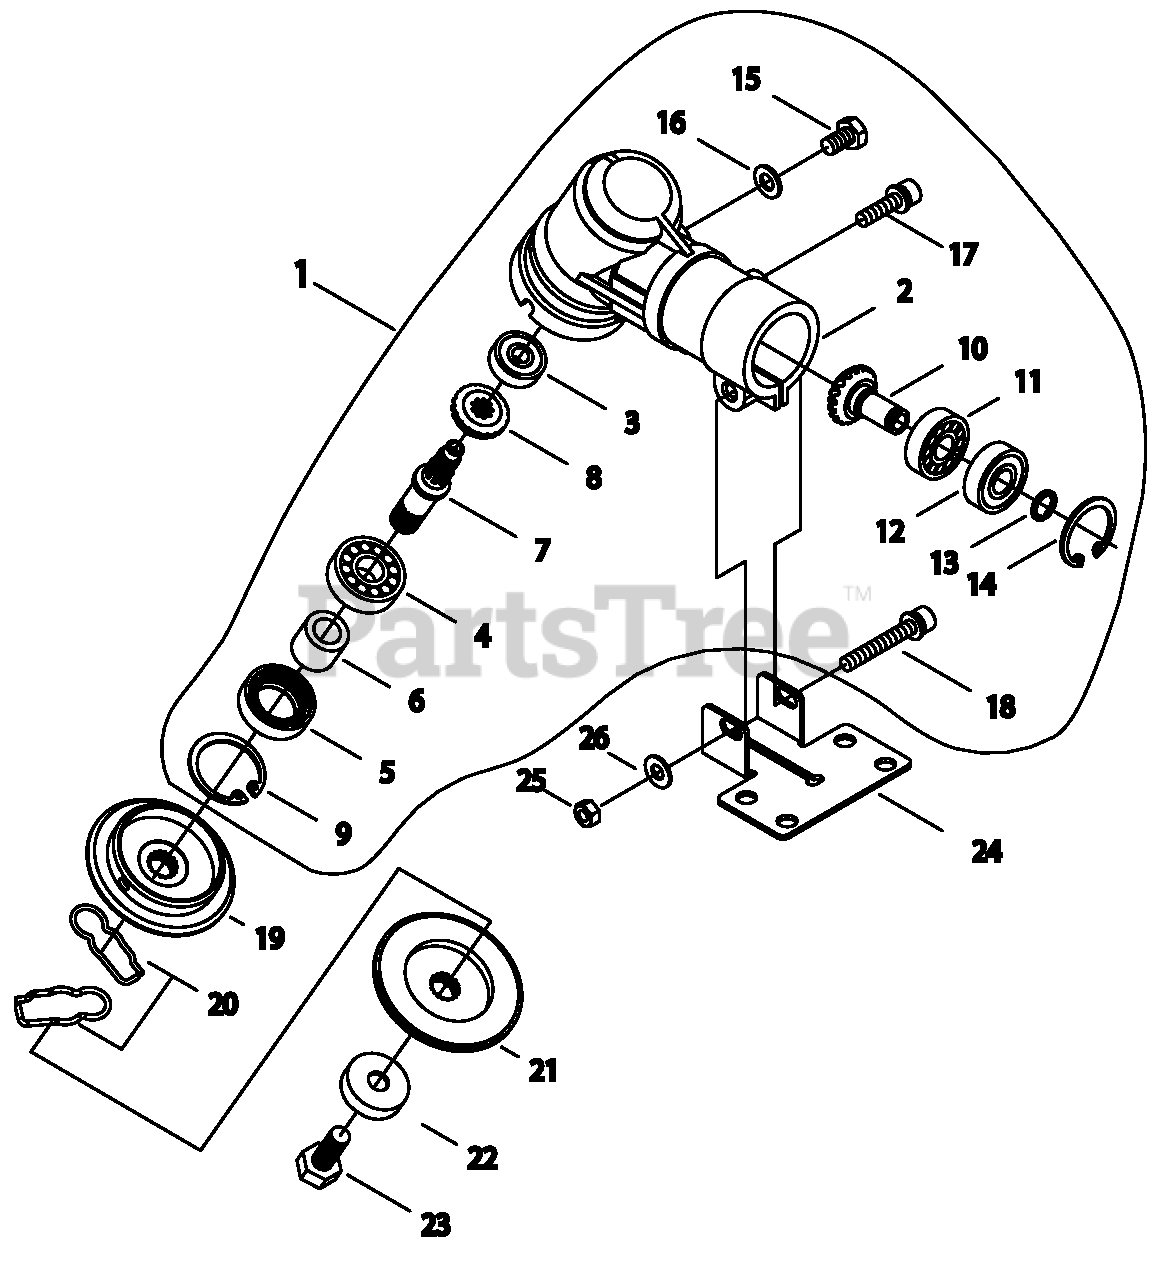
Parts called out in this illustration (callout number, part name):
1	GEAR CASE ASSY
2	CASE, GEAR
3	BEARING, BALL - 6000
4	BEARING, BALL - 6202
5	SEAL, OIL
6	COLLAR
7	GEAR - SHAFT
8	GEAR - BEVEL
9	RING, RETAINING - 35
10	GEAR - SHAFT
11	BEARING, BALL - 6001
12	BEARING, BALL - 6001ZZ
13	RING, RETAINING
14	RING, RETAINING - 28
15	BOLT - 6X10
16	WASHER
17	BOLT - 6X14
18	SCREW - 6X40
19	ADAPTOR, BLADE - UPPER
20	CLIP
21	ADAPTOR, BLADE - LOWER
22	GUARD
23	BOLT - 10 -- LEFT HAND
24	CLAMP - LOWER
25	LOCKNUT - 6
27	WASHER - 6
